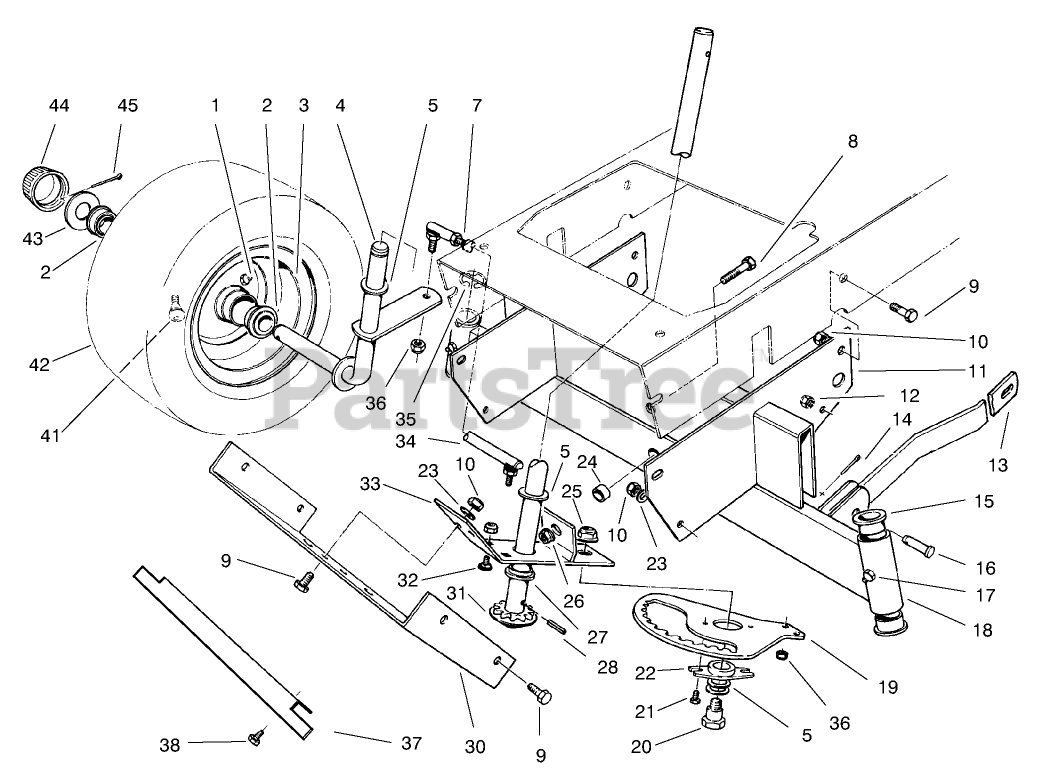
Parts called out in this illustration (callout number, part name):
1	FITTING-GREASE
2	BEARING-WHEEL
5	WASHER-THRUST
7	NUT-JAM
8	SCREW-HH
9	SCREW-HH
10	NUT-LOCK, NI
11	AXLE SUPT WA
12	NUT-HEX
13	ARM-FR DECK SUSP
14	PIN-COTTER
15	BEARING-FLANGE
16	PIN-CLEVIS
17	FITTING-GREASE
18	FRONT AXLE WA
19	GEAR-SECTOR
21	SCREW-HWH
22	BUSHING-SECTOR
23	WASHER-PLAIN
24	SPACER-AXLE, FRONT
25	NUT-HF
26	NUT-HF
27	BEARING-FLANGE
28	PIN-ROLL, SLOTTED
30	COVER-FRONT
31	STRG SHAFT WA
32	SCREW-CARR
33	STRG RACK BRKT WA *B
34	TIE-ROD
35	E-RING
36	NUT-LOCK
37	GUARD-FRONT
38	SCREW-HWHTF
43	WASHER-PLAIN
44	CAP-HUB
45	PIN-COTTER
